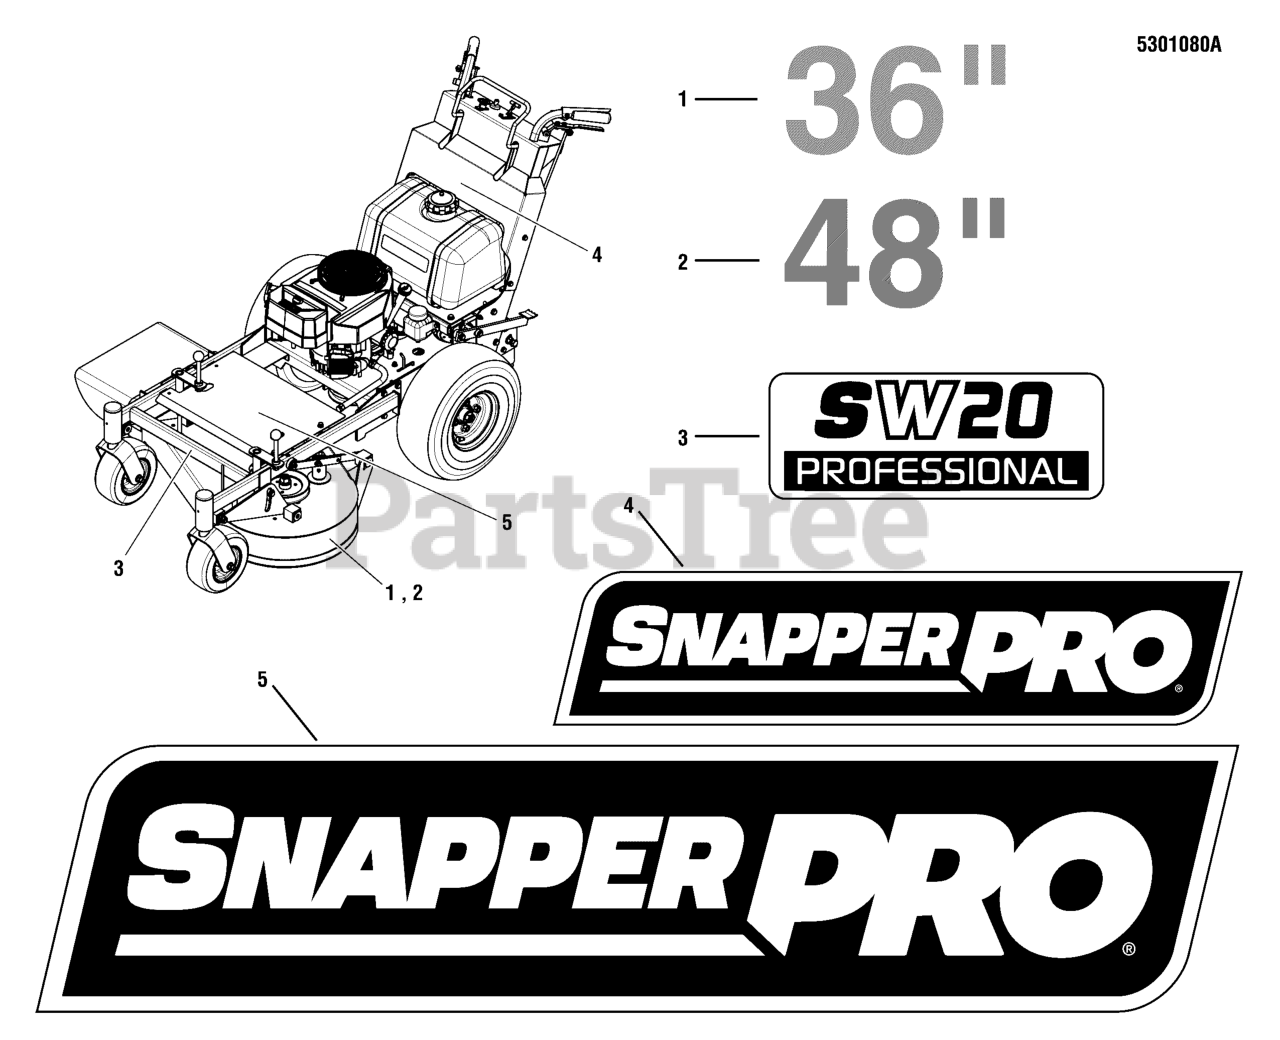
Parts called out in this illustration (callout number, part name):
1	DECAL, 36"
2	DECAL, 48
3	DECAL, SW20 (2014)
4	DECAL, SNAPPER PRO LOGO, SMALL
5	DECAL, SNAPPER PRO LOGO, LARGE
